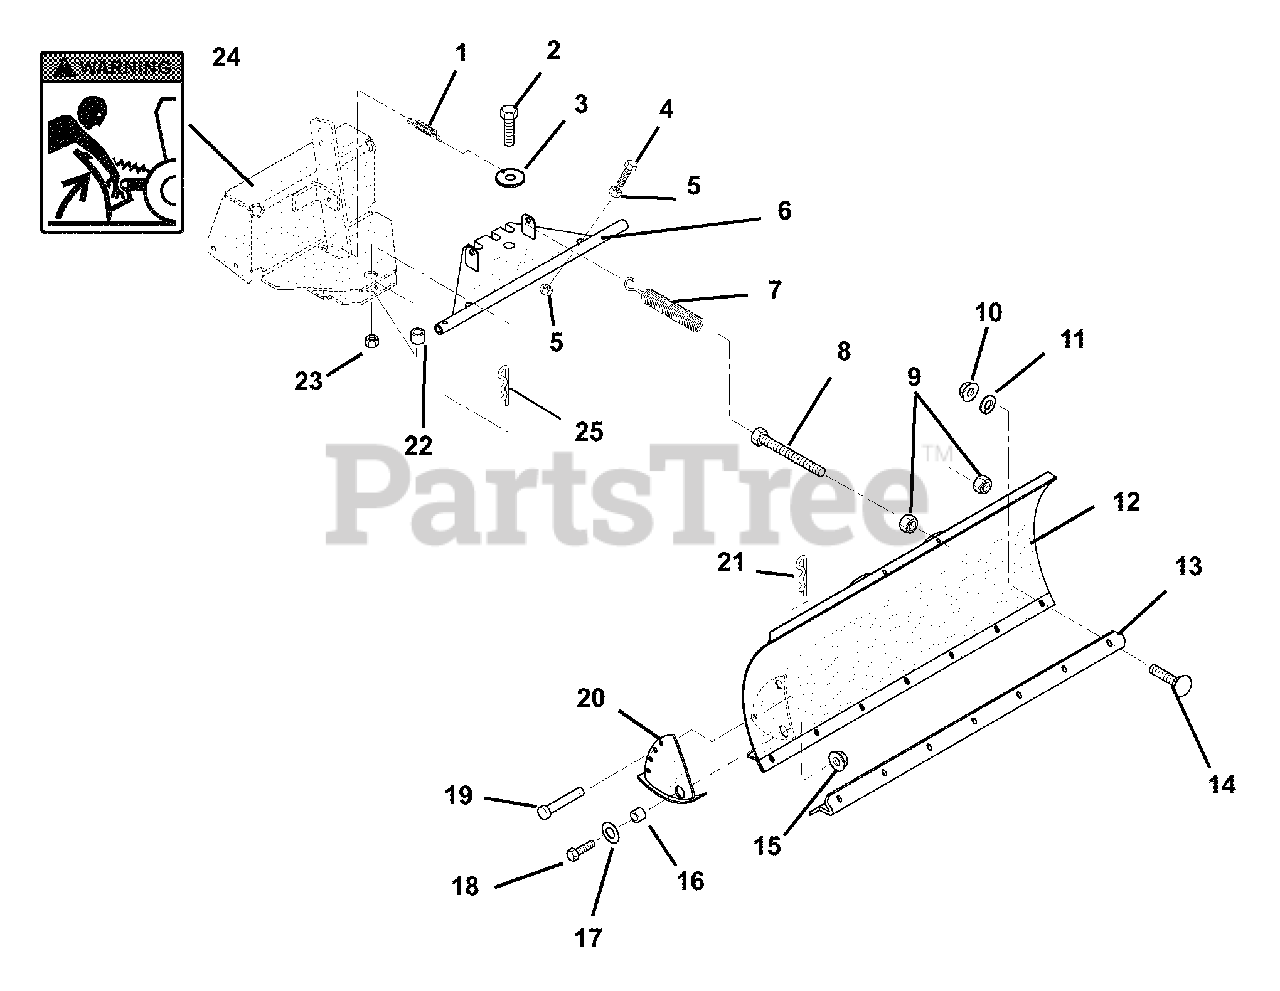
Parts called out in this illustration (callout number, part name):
1	SPRING,LATCH
2	BLT-HEX .75-10X3.00 GR5 YWZC
3	WSHR, SPECIAL
4	@BLT-HEX .50-13X2.00 GR5 YWZC
5	@NUT-HEX .50-13 YWZC
6	WMT,PIVOT PLATE
7	SPRING,BLADE ADJUSTMENT
8	BLT,HEX 3/8-16X4.00 FULL TH'D
9	@NUT-HEX .38-16 YWZC
10	@NUT-LK-CTR .31-18 YWZC
11	@WSHR-LK .31X.078 REG YWZC
12	WMT,54"BLADE(AGRI-FAB)
13	PLATE,WEAR
14	@BLT-RDHDSQNK .31-18X.75 G5YZ
15	@NUT-LK-CTR .38-16 YWZC
16	BUSHING,SKID PIVOT
17	@WSHR-FL-STL.406X.812X.065 YWZ
18	@BLT-HEX .38-16X1.00 GR5 YWZC
19	PIN, CLEVIS .312 X 1
20	SKID,54"BLADE
21	PIN-HAIR INT .08X.18X1.18 YWZC
22	SPACER, .753X1.00X1.60
23	NUT-LK-JAM-NYL .75-10 YWZC
24	DECAL, PINCH POINT
25	PIN-HAIR-INT .15X2.937 YWZC
